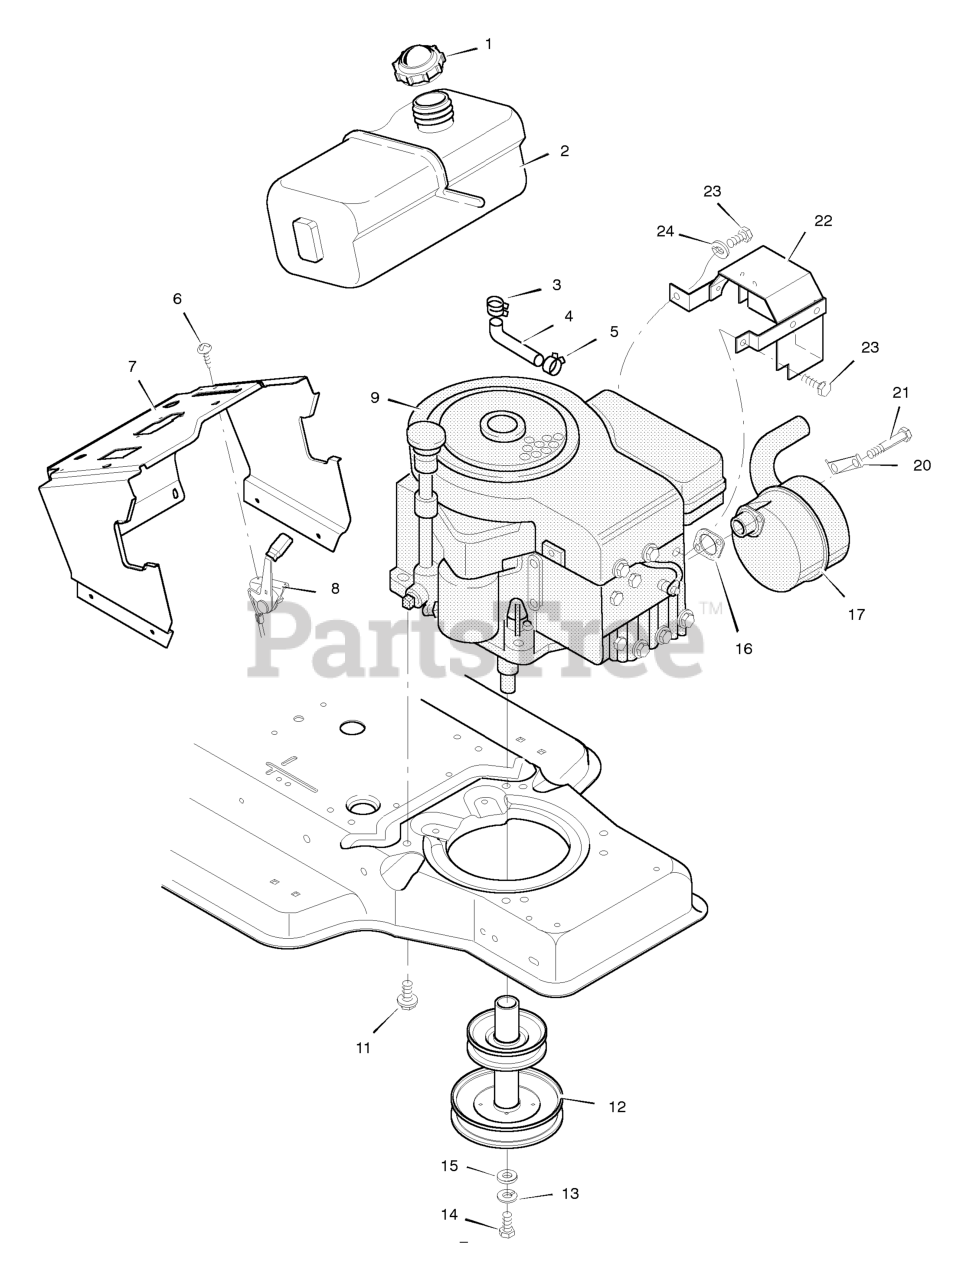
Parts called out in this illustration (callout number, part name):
1	Fuel Cap
2	Fuel Tank
3	Hose Clamp
4	Fuel Line
5	Hose Clamp
7	Support, Dash
8	Throttle Control
9	Engine *
11	Bolt, Engine Mount
12	Stack Pulley Assembly
13	Lockwasher
14	Bolt, Hex
16	GASKET, Exhaust
17	Muffler
20	Lock, Screw
22	Shield, Heat
